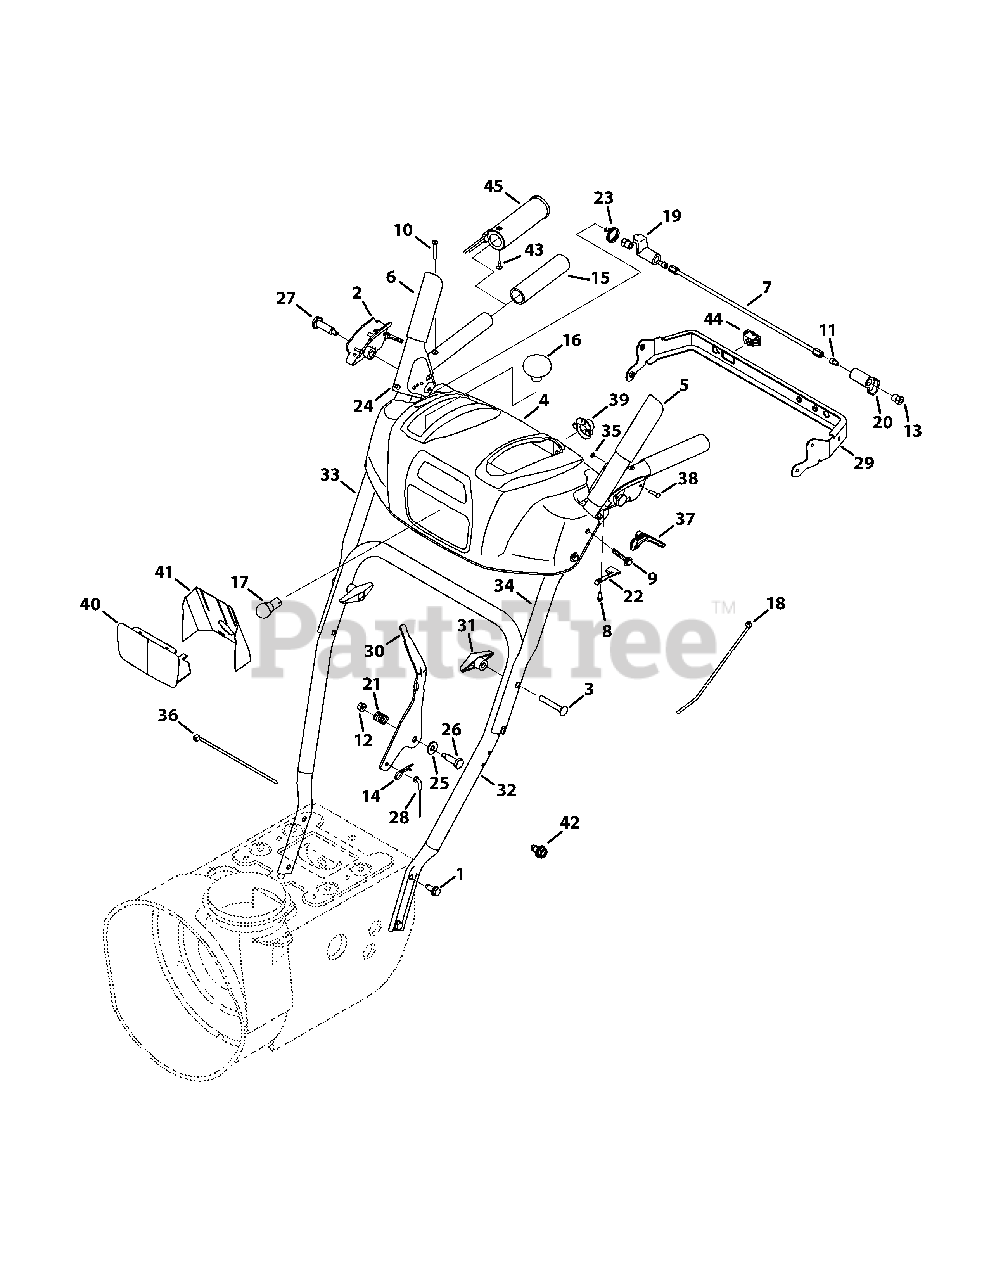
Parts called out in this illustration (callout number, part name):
1	Hex Screw, 5/16-18 x .750
2	Handle Clutch Lock LH Assy
2	Handle Clutch Lock RH Assy
3	Carriage Screw, 5/16-18 x 2.25
4	Handle Panel, includes Ref. 40 & 41
5	Handle Engagement Assembly LH
6	Handle Engagement Assembly RH
8	Screw, 8-16 x 0.50
9	Screw, 1/4-20 x 1.625
10	Screw, 10-24 x 1.375
11	Socket Screw, 1/4-20 x .50
12	Flange Lock Nut, 1/4-20
13	Shoulder Nut, 1/4-20
14	Click Pin, .092 x 1.64
15	Handle Grip (524/526/528 SWE)
16	Shift Knob
18	Cable Tie
20	Clutch Lock Cam
21	Compression Spring
22	Clutch Lock Spring
23	Torsion Spring
24	Rubber Bumper
25	Flat Washer, .385 x .87 x .06
26	Shoulder Screw, .374 x 1.05
27	Shoulder Screw, 1/4-20 x 1.345
28	Speed Cable Selector
29	Panel Bracket
30	Shift Lever
31	Wing Knob
32	Lower Handle
33	Upper Handle RH
34	Upper Handle LH
36	Cable Tie
37	Clutch Trigger
39	Light Socket
41	Lens Label
42	Screw, TT, 1/4-20 x .500 (For ground wire)
43	AB Screw, #10-16 x .625 (530 SWE)
44	Heated Grip Switch (530 SWE)
45	Heated Grip (530 SWE)
